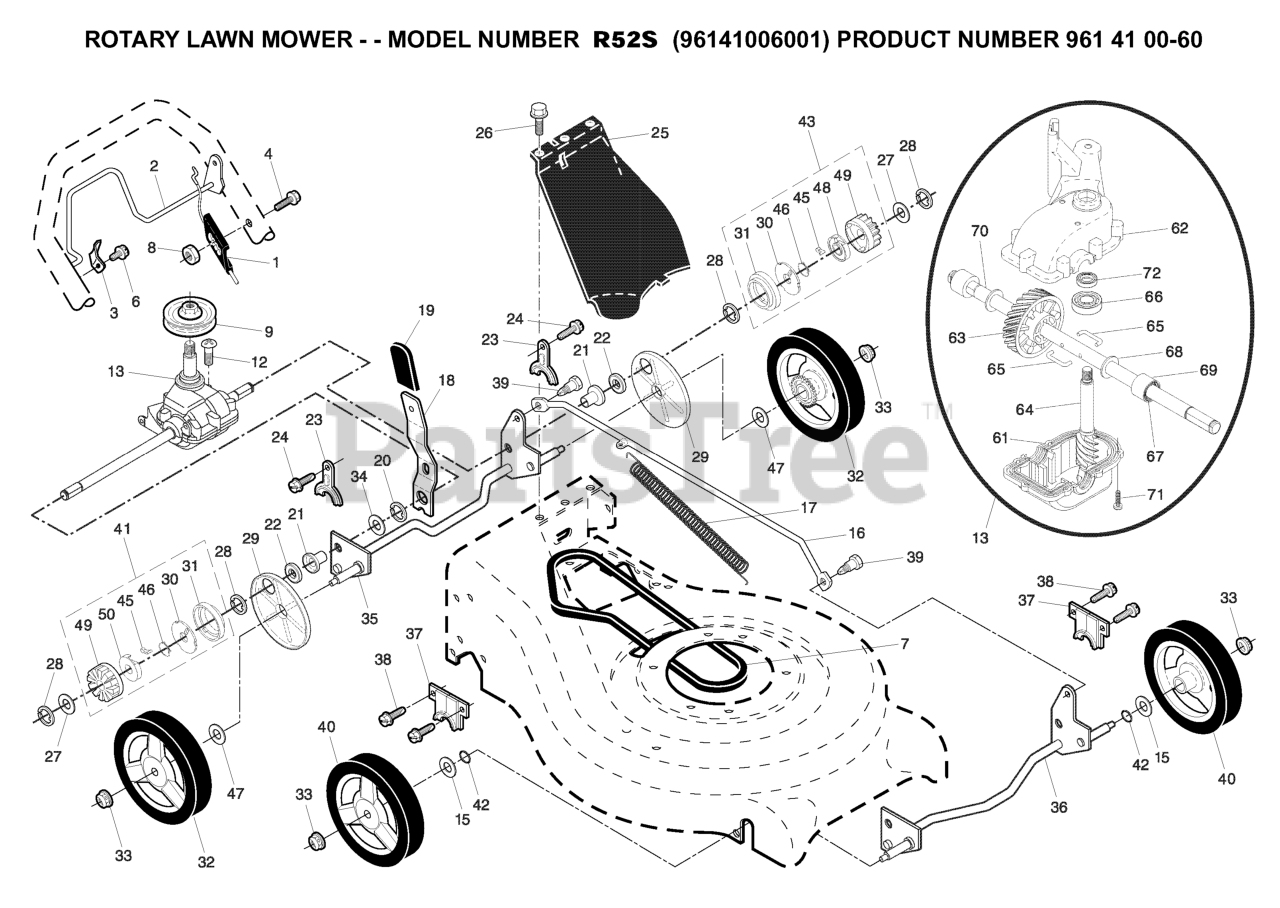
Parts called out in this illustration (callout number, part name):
1	Battery 12 Volt 25 Amp
2	BOLT.HEX.1/4.X.3/4.DICHROMATE
8	BOX.BATTERY.FENDER
16	SWITCH INTERLOOK PUSH-IN
21	HARNESS.W/LIGHT SOCKET
24	BATTERY CABLE GT
25	CABLE BATTERY
26	FUSE 20AMP
27	NUT
28	CABLE T
29	SWITCH.SEAT.DP W/RAMPS
30	SWITCH.IGN.DELTA.W.LGH.ROS
33	KEY.CHAIN.BLISTER.PACK.GEN.INT
40	HARNESS.IGN.CABLE.REG.
41	BOLT
42	TERMINAL COVER
43	SOLENOID.W/BRASS.PLUNGER
79	BULB HOLDER ASM.
90	COVER TERMINAL
92	HARNESS.PIGTAIL.CONSLE
93	SCREW.PLASTITE
94	MODULE.REVERSE.ROS
